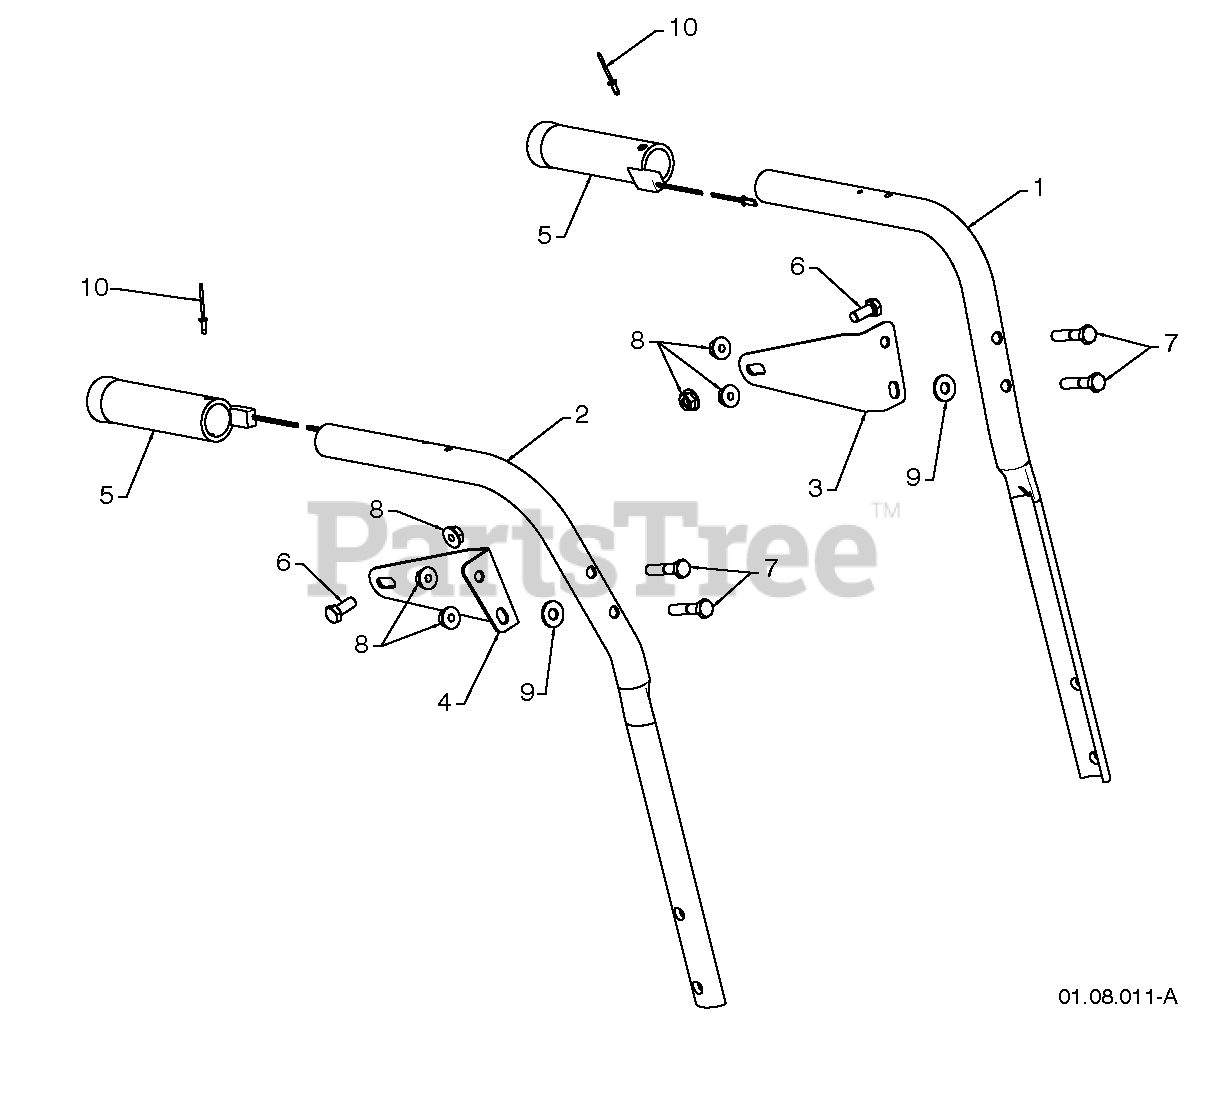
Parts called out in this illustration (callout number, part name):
1	PLOW HANDLE LH
2	PLOW HANDLE RH
3	PANEL BRACKET LH
4	PANEL BRACKET RH
5	HEATED HANDLE GRIP
6	SCREW 5/16-18 X .750
7	SCREW 5/16-18 X 1.50
8	NUT 5/16-18
10	POP RIVET 1/8
